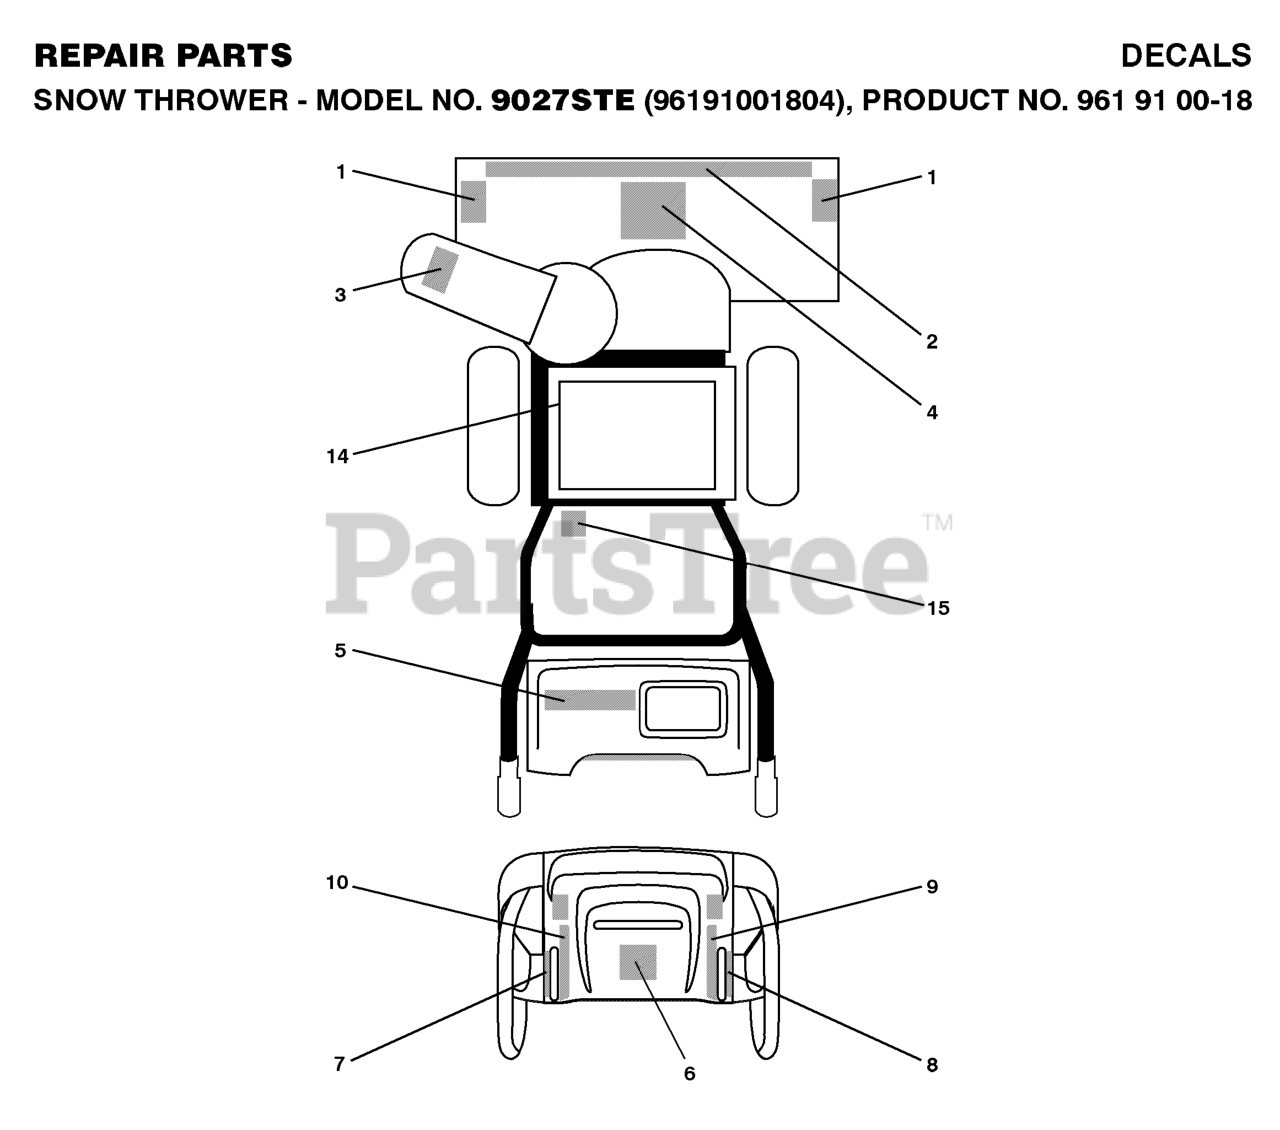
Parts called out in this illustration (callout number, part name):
1	DECAL.AUGER.SAFETY.
3	DECAL.CHUTE.SAFETY.
4	DECAL.AUGER."
6	DECAL.CONSOLE.INSTRUCTION
7	DECAL.POWER.STEER.LT.TRIG.INT
8	DECAL.POWER.STEER.RT.TRIG.INT
10	DECAL.REM.DEFLECTOR.LT
14	DECAL.BELT.GUARD.
15	DECAL.FENDER
